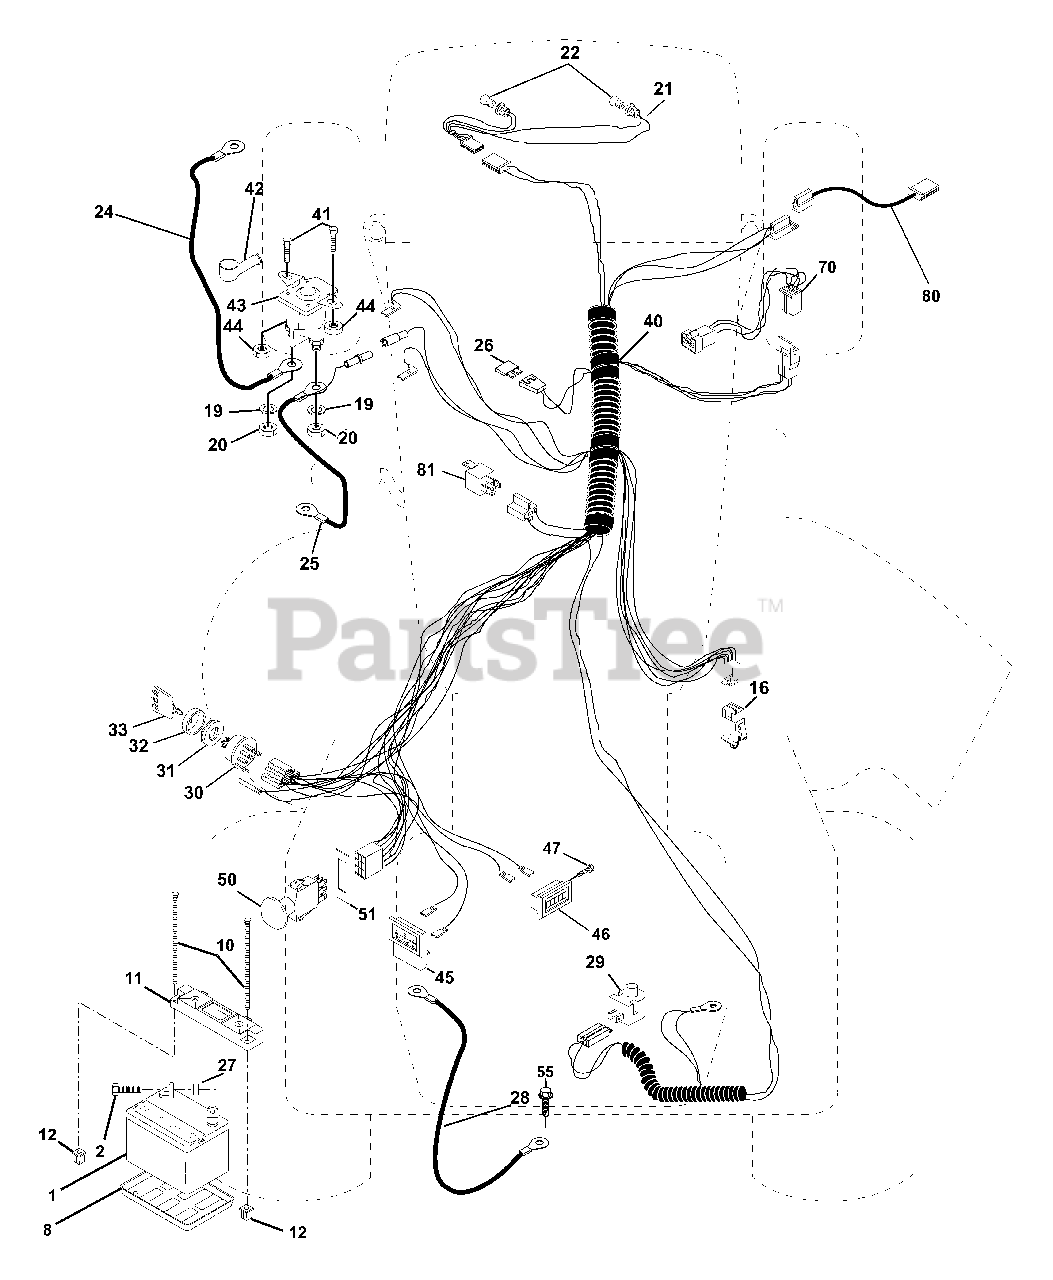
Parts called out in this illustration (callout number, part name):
1	Battery 12 Volt 25 AMP
2	Bolt Hex Hd 1/4-20unc X 3/4
8	Tray Battery 7.80 x 5.25 Blk
10	Bolt Btr Frt 1/2-20 x 7.5 Zinc
11	Holddown Battery Front Mount
12	Nut Push Nylon 1/4" Battery Frt
16	Switch Interlock Push-In
19	Washer Lock 1/4
20	Nut Jam Hex 1/4-20 Unc
21	Harness Asm Light W/4152j
22	Bulb Light #1156
24	Cable Battery 6 Ga 11" red
25	Cable Battery 6 Ga 44" red w/16 wire
26	Fuse 30 AMP Auto Green
27	Nut Keps Hex 1/4-20 Unc
28	Cable Ground 6 Ga 21" black
29	Switch Plunger Normal Op Olive
30	Switch Ign 4 pos w/lights
31	Nut Ignition
32	Cover Sw Ignition
33	Key Ign Modelled Generic
40	Harness Ign.
41	Bolt Blk Fin Hex 1/4 - 20 x 1/2
42	Cover Terminal Red
43	Solenoid
44	Nut Keps Hex 1/4-20 Unc
46	Meter Hour
47	Screw 10-24 x 1/2 Black
50	Switch PTO 3PDT Black Delta 96
51	Ring Retainer PTO
55	Screw Thdrol 5/16-18 x 1/2 Tyt
70	Harness, Eng Kohl Cmd-L Dual
80	Harness Clutch Evx
81	Relay Asm.
